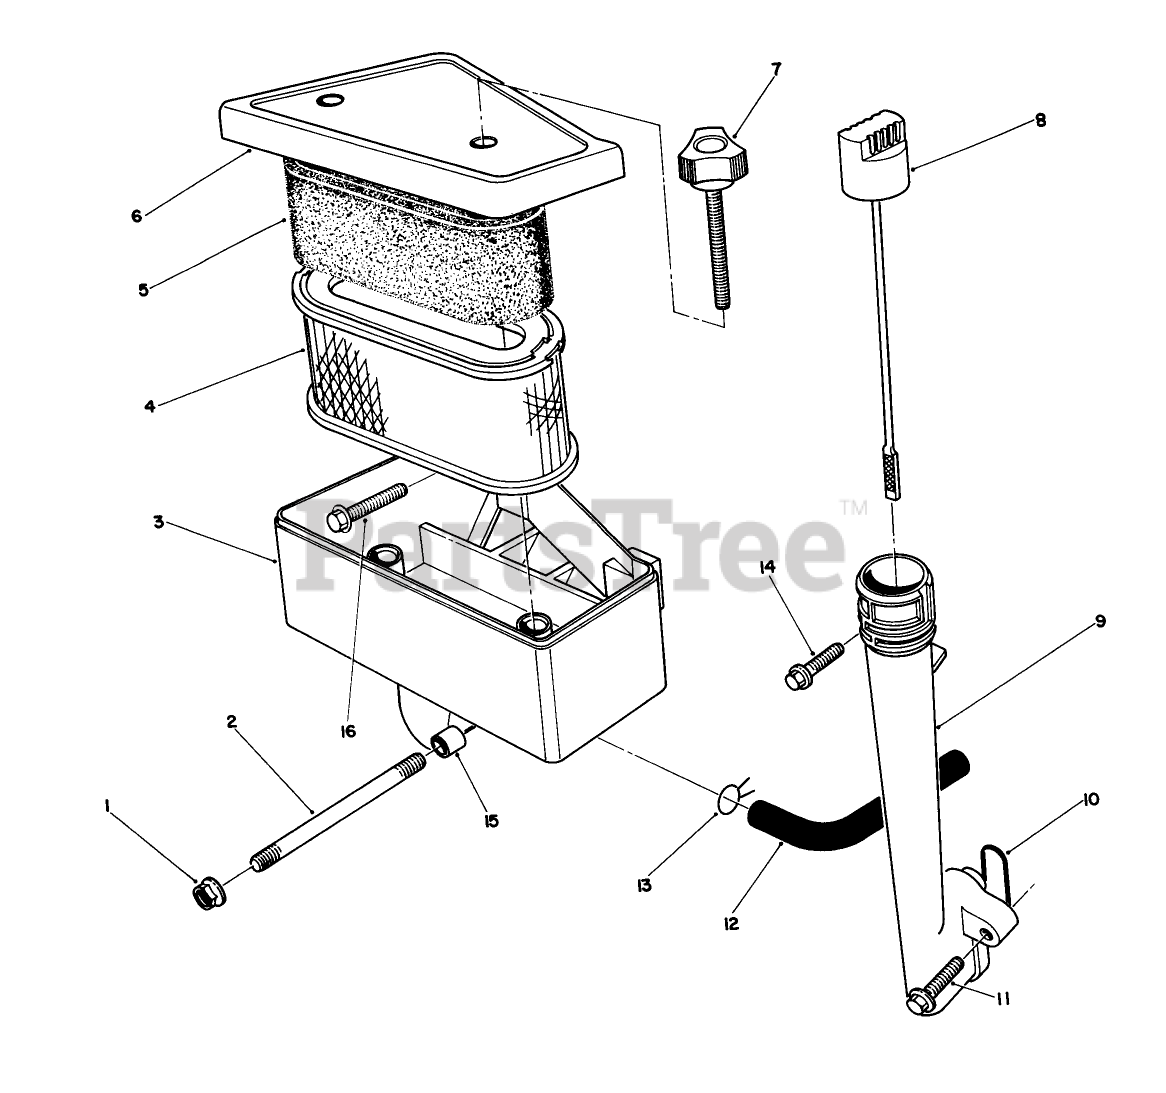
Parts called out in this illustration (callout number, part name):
3	AIR CLEANER BODY
4	AIR FILTER ELEMENT
5	Filter-Foam
6	AIR CLEANER COVER *B
7	RETAINER - COVER
10	O-RING
13	CLAMP F/W ENGINE
15	SPACER
